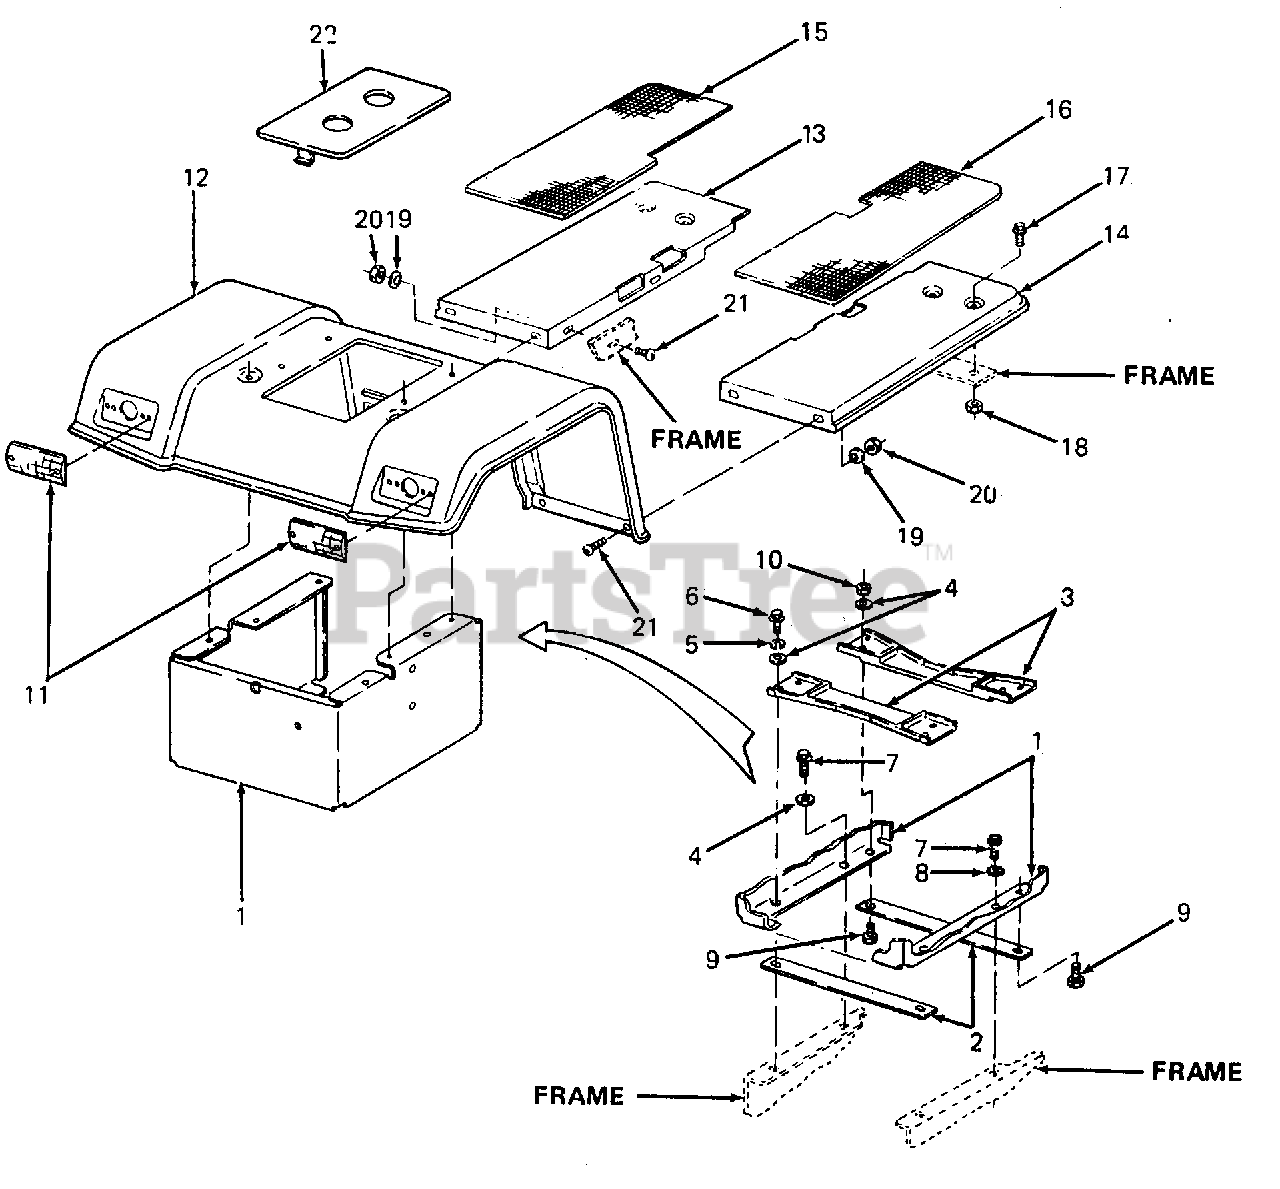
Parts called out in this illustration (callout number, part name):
1	Box, Fender Mounting
2	Plate, Reinforcement
3	Tray, Battery
4	Washer, Flat, .344 X .875 X .06 Thk
5	Washer, Lock, 5/16
6	Screw, Hex Wash Hd Tapp, 5/16-18 X .88 Lg
7	Screw, Hex Wash Hd Tapp, 5/16-18 X .50 Lg
8	Washer, Int Ext Lock, 5/16 X 7/8
9	Screw, Hex Cap, 5/16-18 X .75 Lg GR5
10	Nut, Hex Patch Lock, 5/16-18
11	Reflector
16	Pad, RH - Foot Rest
17	Screw, Hex Wash Hd Tapp, 5/16-18 X .62 Lg
18	Nut, Hex Center Lock, 5/16-18 GR5
19	Washer, Bell, .265 X .75 X .062 Thk
20	Nut, Hex, 1/4-20
21	Screw, Truss Mach, 1/4-20 X .50 Lg
22	Cover, Battery
